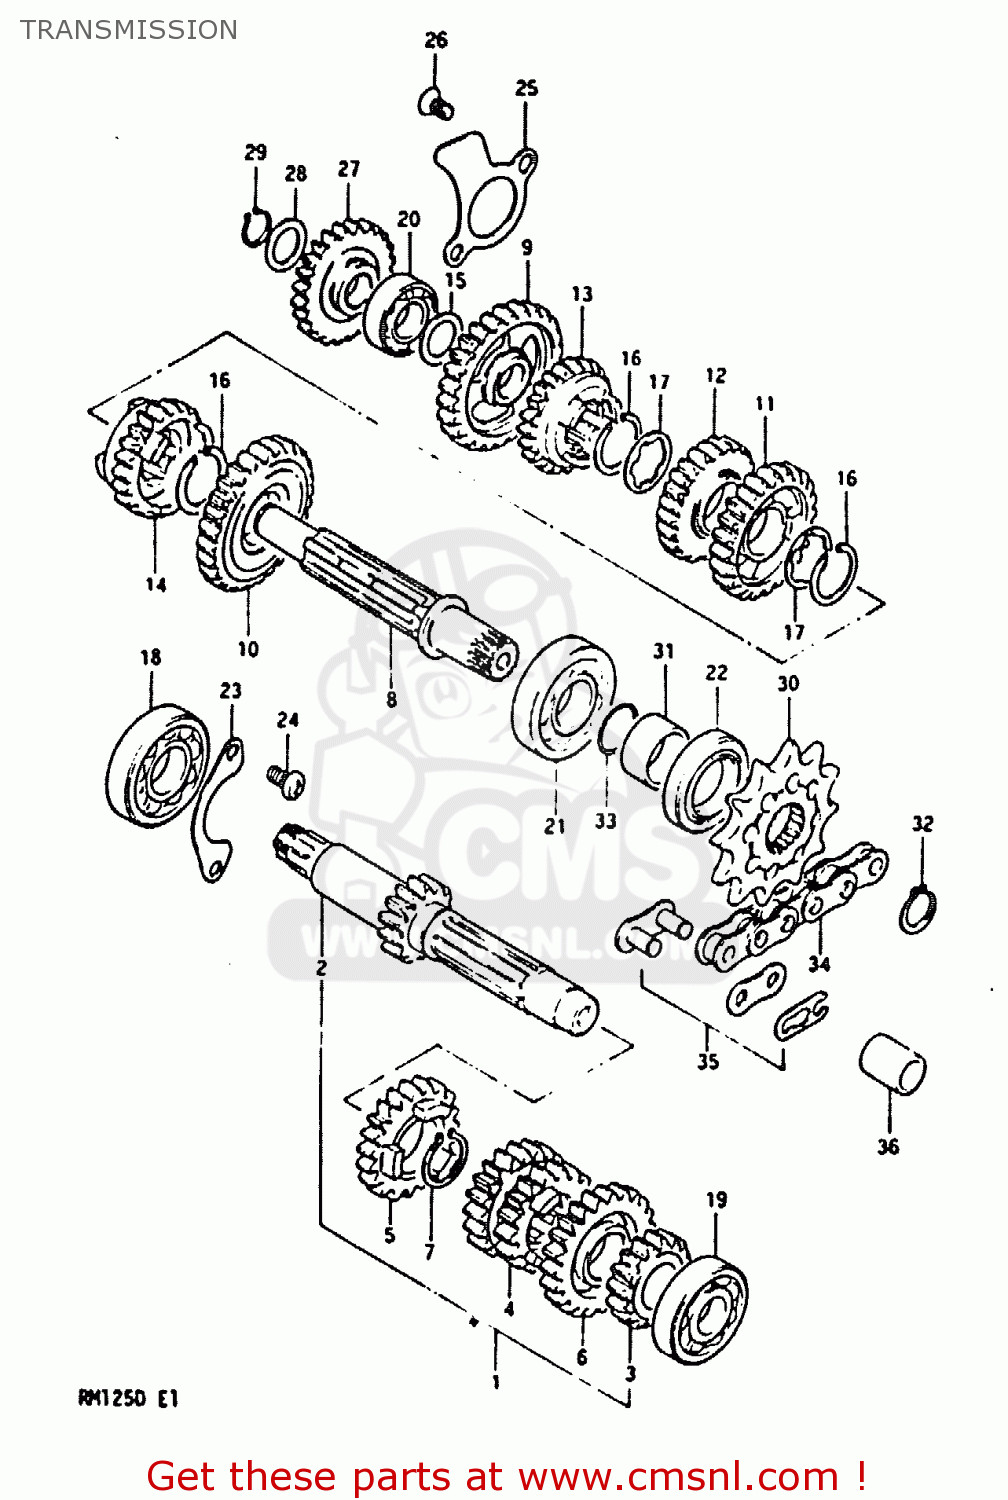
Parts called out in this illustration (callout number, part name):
1	SHAFT,COUNTER
2	SHAFT,COUNTER
3	GEAR,SECOND DRIVE
4	GEAR,THIRD/FOURTH DRIVE
5	GEAR,FIFTH DRIVE
6	GEAR,SIXTH DRIVE
7	CIRCLIP
8	SHAFT,DRIVE
9	GEAR,FIRST DRIVEN
10	GEAR,SECOND DRIVEN
11	GEAR,THIRD DRIVEN
12	GEAR,FOURTH DRIVEN
13	GEAR,FIFTH DRIVEN
14	GEAR,SIXTH DRIVEN
15	WASHER,THRUST
16	CIRCLIP
17	WASHER,LOCK
18	Bearing
19	BEARING
20	BEARING, RH
21	BEARING(20X47X14)
22	SEAL,OIL(25X40X7)
23	RETAINER,CNTR SHAFT BEARING
24	SCREW 6X12
25	RETAINER,DRIVESHAFT
26	SCREW
27	GEAR,KICK STARTER IDLE
28	WASHER,THRUST
29	CIRCLIP,15MM
30	SPROCKET,ENGINE
31	SPACER(20X25X12.5)
32	CIRCLIP
33	O RING(D:1,ID:19.5)
34	CHAIN ASSEMBLY,DRIVE
35	JOINT ASSEMBLY,CHAIN
36	CUSHION
